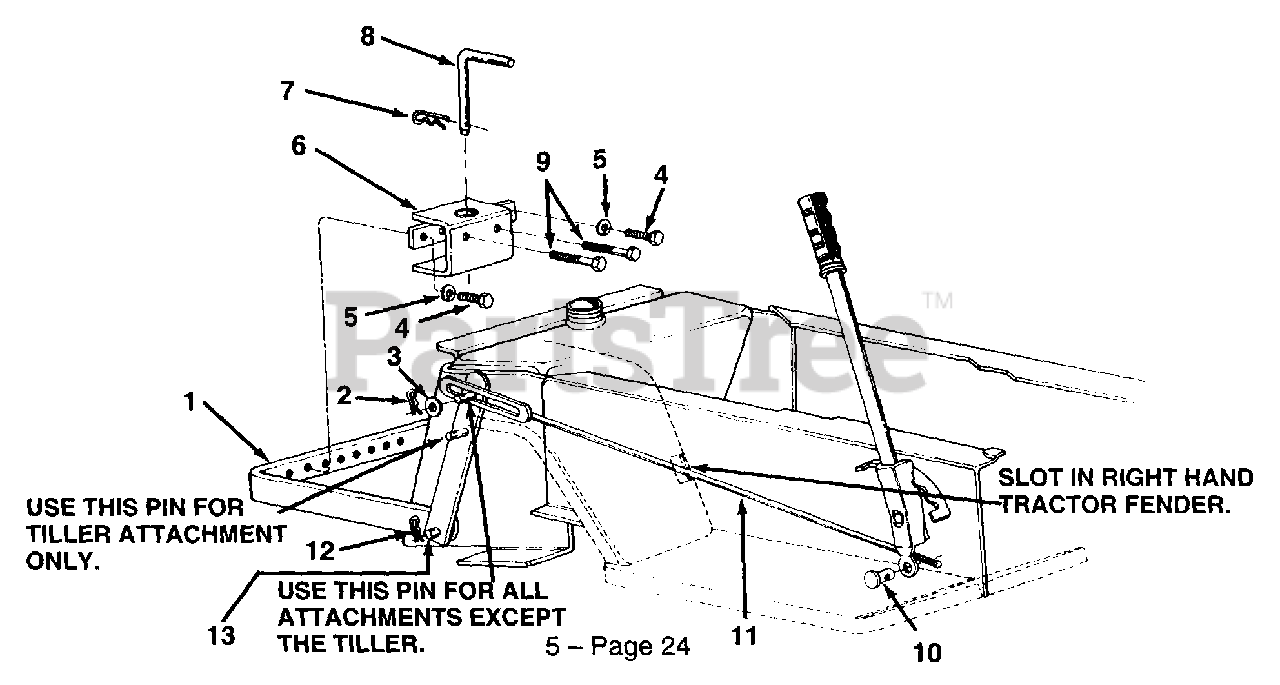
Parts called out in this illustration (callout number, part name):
3	Fl-Wash. 1/2" I.D.
4	Hex Bolt 1/2-13 x 1.0" Lg.
5	L-Wash. 1/2" I.D.
6	Hitch Brkt. Ass'y.
7	Internal Cotter Pin 5/8" Dia.
8	Hitch Pin
9	Hex Bolt 1/2-13 x 3.0" Lg.
10	Adjustment Ferrule
13	Hitch Rod
